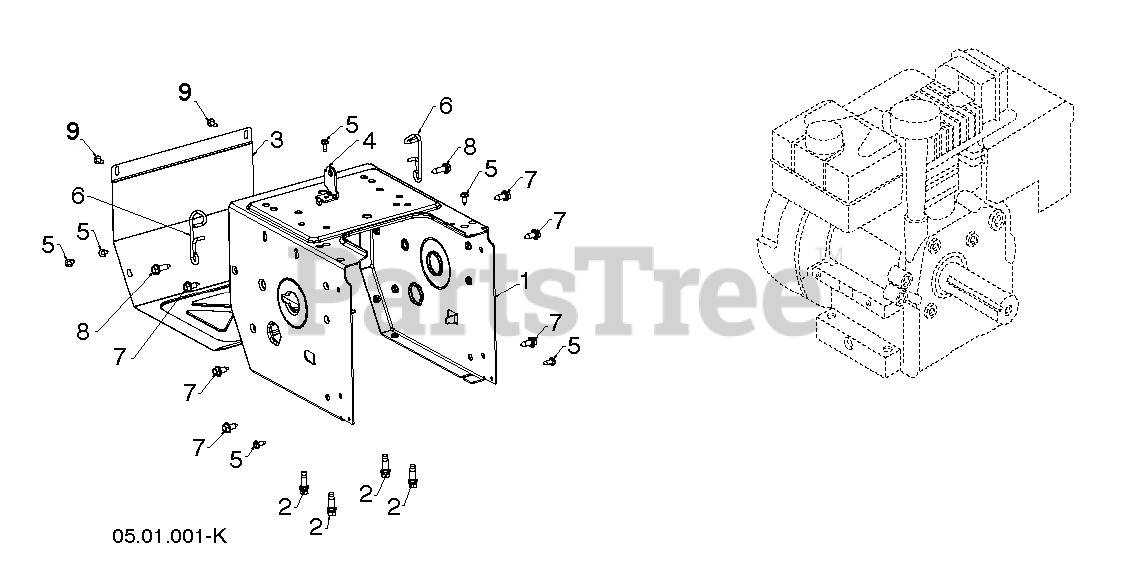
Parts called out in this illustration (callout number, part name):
1	FRAME.GEAR.CASE.ORANGE
1	FRAME MS 668
2	BOLT 3/8-16X1-1/8
3	COVER COVER.FRAME MS668 ORANGE
4	BRACKET.SHIFTER.BZP
5	SCREW.HEX HEAD W/COLLAR 1/4-20
6	WIREFORM.SUPPORT.CABLE
7	BOLT.HEX.HD.WASHER.5/16-18X.75
8	SCREW HEX_SERR_HD_5_16-18X1.0
9	SCREW
9	SCREW.HEX HEAD W/COLLAR 1/4-20
